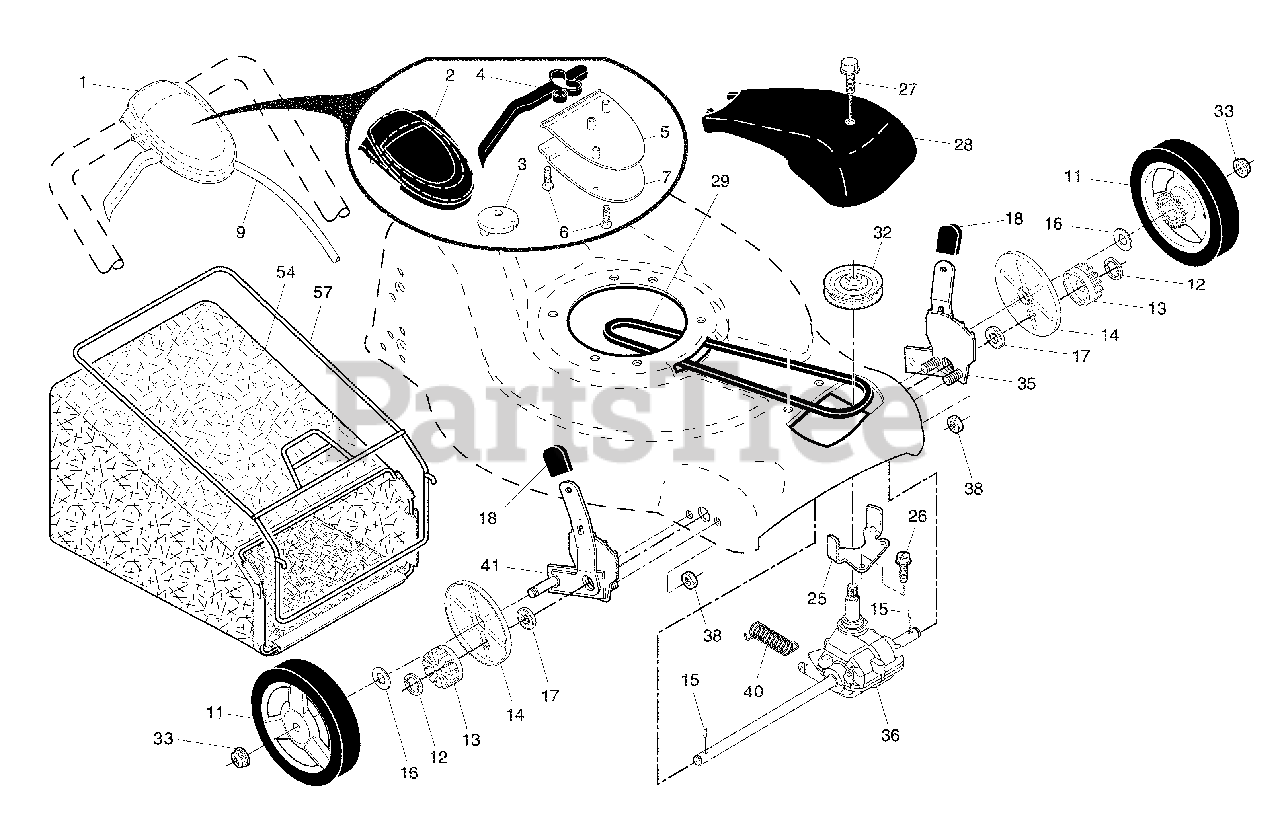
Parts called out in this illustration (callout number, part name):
1	Drive Control Assembly
2	Cover, Drive Control, Upper
4	Lever, Drive Control
5	Cover, Drive Control, Lower
7	Mounting Bracket, Drive Control
9	Cable, Drive
11	Wheel & Tire Assembly
14	Dust Cover
15	Pawl, Drive
16	Washer 1/2 x 1-1/2 x .134
17	Bearing, Wheel Adjuster
18	Selector Knob
25	Belt Keeper
26	Screw, Hi-Lo Thread
27	Pan Head Tapping Screw #10-24 x 2-3/4
28	Drive Cover
32	Drive Pulley
33	Locknut, Hex
35	Kit, Wheel Adjuster, LH
36	Gearcase Assembly, Complete
38	Locknut, Hex 1/4-20
41	Kit, Wheel Adjuster, RH
54	Grassbag Assembly
57	Frame, Grassbag
